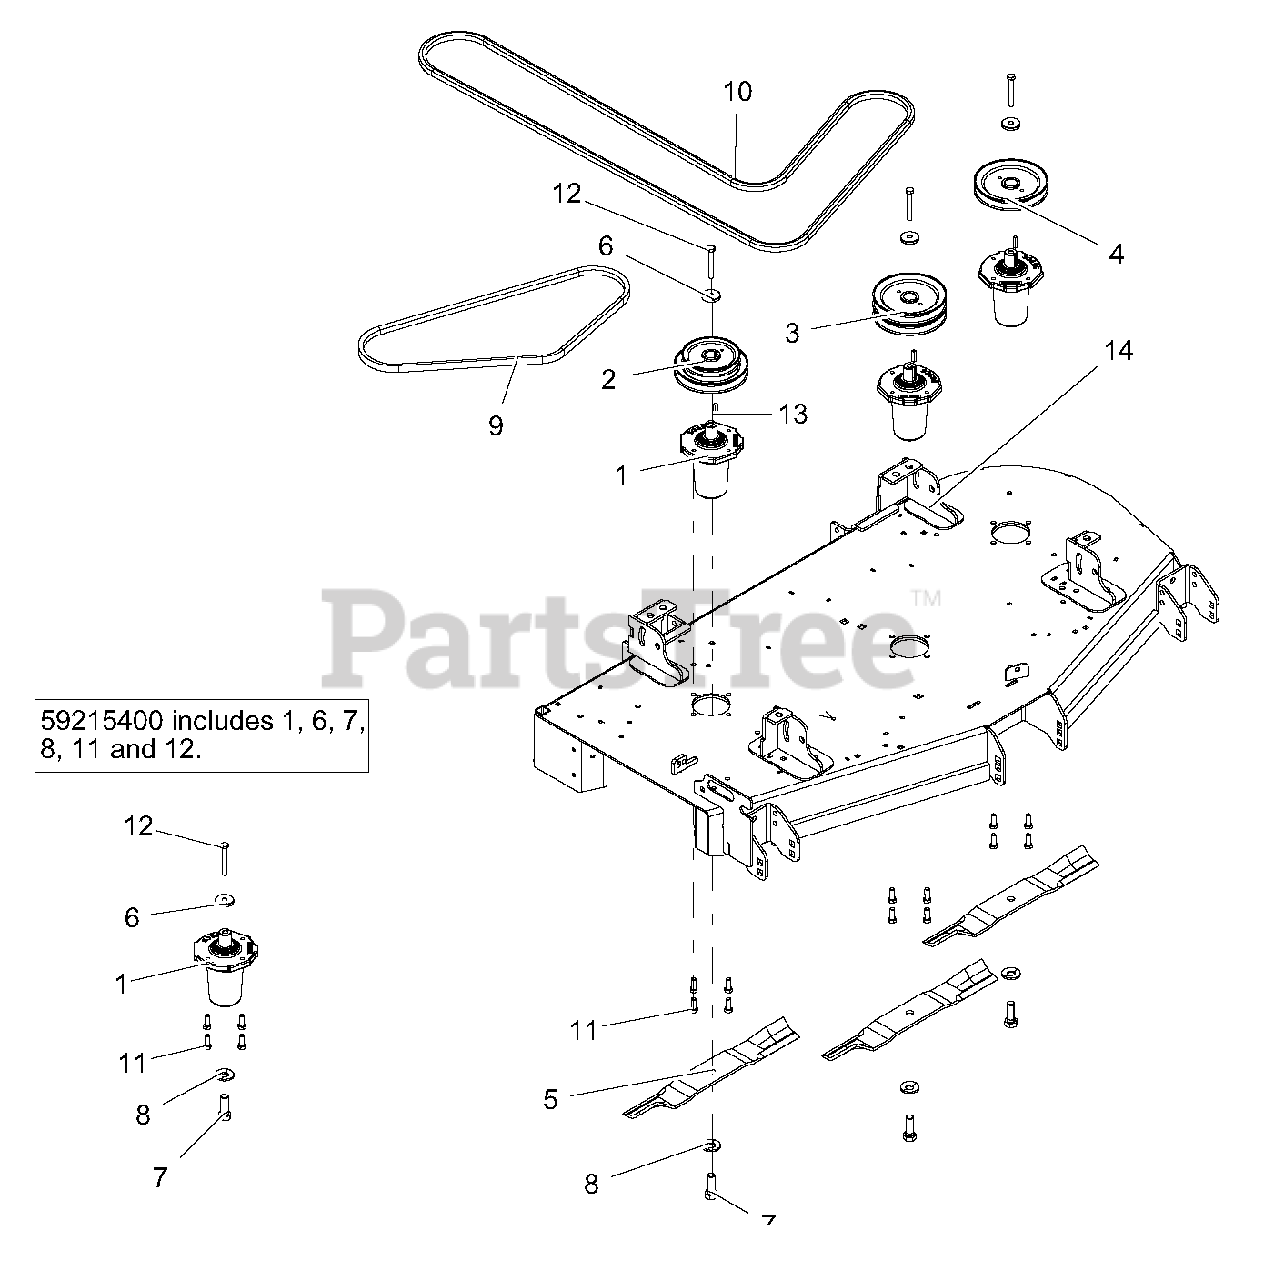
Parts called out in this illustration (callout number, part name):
1	ASM, SPINDLE - G3500
2	PULLEY, DOUBLE -1" ID X 6.00" & 4.75" OD
3	PULLEY, DOUBLE -1" ID X 6.00" OD-BLACK
4	PULLEY, SINGLE -1" ID X 6.00" OD-BLACK
5	BLADE, 18.00" MOVER (HI-LIFT)
6	RETAINER, SHEAVE SPINDLE
7	BLT, HEX .62-18X1.75 GR8 YWZC
8	WSHR, BLVL .63X1.625X.14
9	BELT, B 56.00 RAW COGGED
10	BELT, B-RAW EDGE COGGED
11	BLT-HEX .38-16X1.00 GR5 YWZC EP30
12	BLT-HEX .38-16X2.75 GR8 YWZC
13	KEY-SQ .250X.250X1.00 RC 40-50
14	WLDMT, 52" PT200 SIDE DISCHARGE DECK-RED
